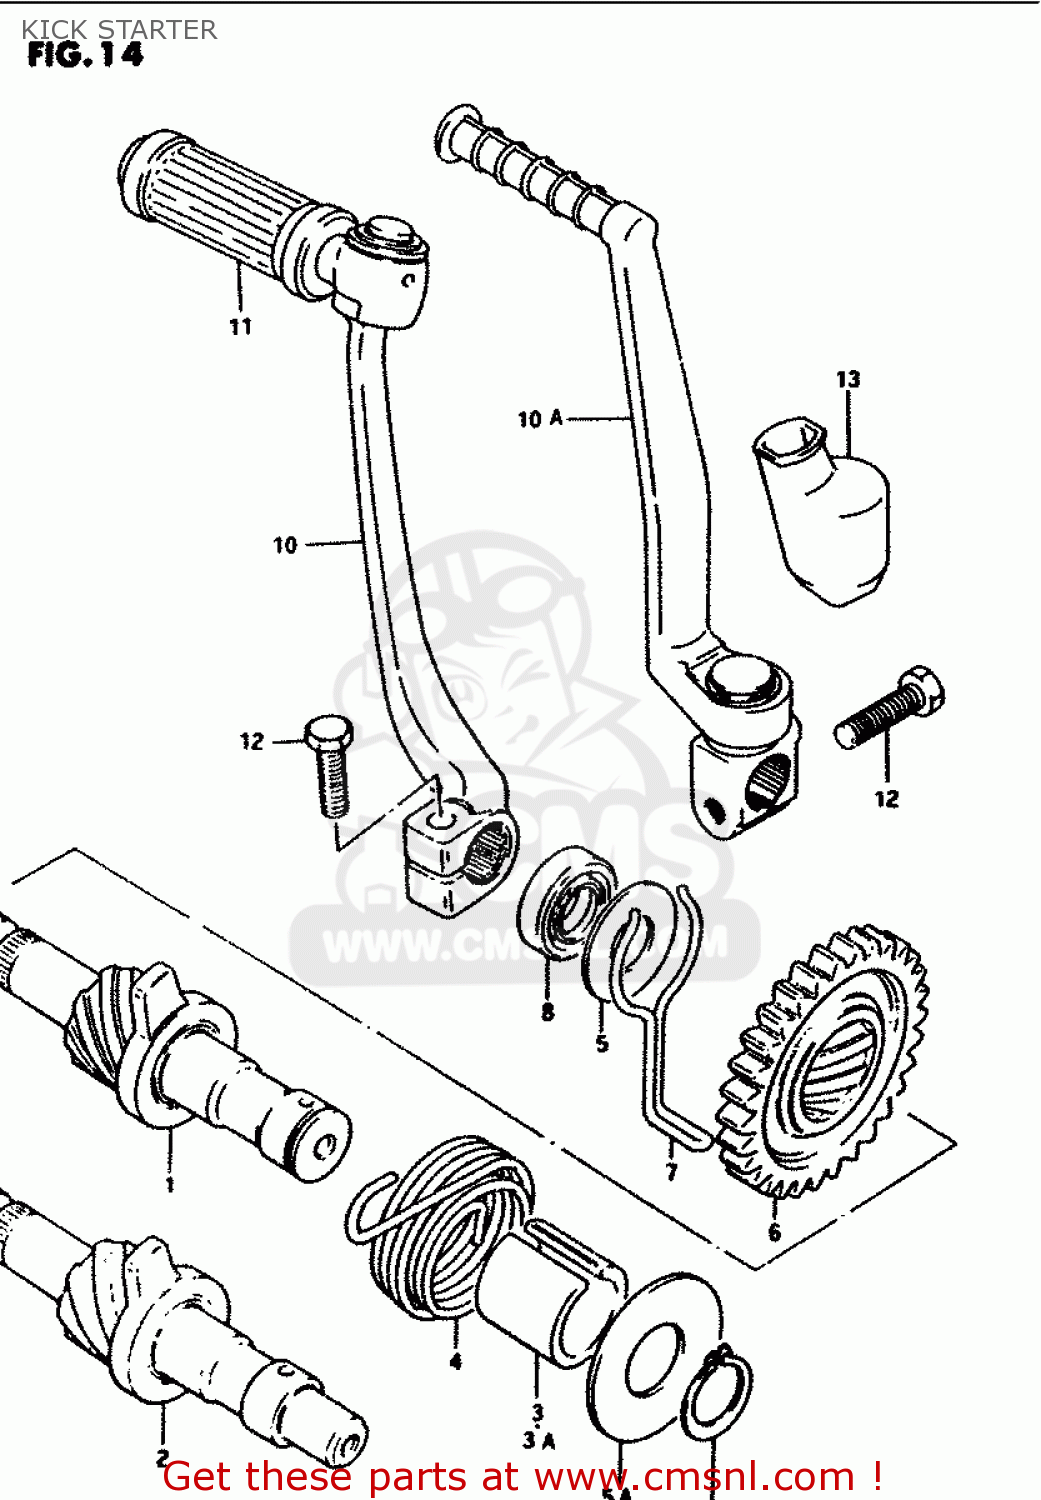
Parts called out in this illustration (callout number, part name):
1	SHAFT,KICK STARTER
2	SHAFT,KICK STARTER
3	GUIDE,KICK STARTER SFT SPRING
3A	GUIDE, SPRING (L:20.2)
4	SPRING
5	WASHER
5A	WASHER(16.2X38X2.3)
6	GEAR,KICK STARTER DRIVE(NT:30)
7	RETAINER,SNAP
8	SEAL,OIL(14X24X6)
9	CIRCLIP 16MM
10	LEVER ASSY
10A	LEVER ASSY,KICK STARTER
11	RUBBER,KICK STARTER PEDAL
12	BOLT
13	COVER,KICK STARTER PEDAL
